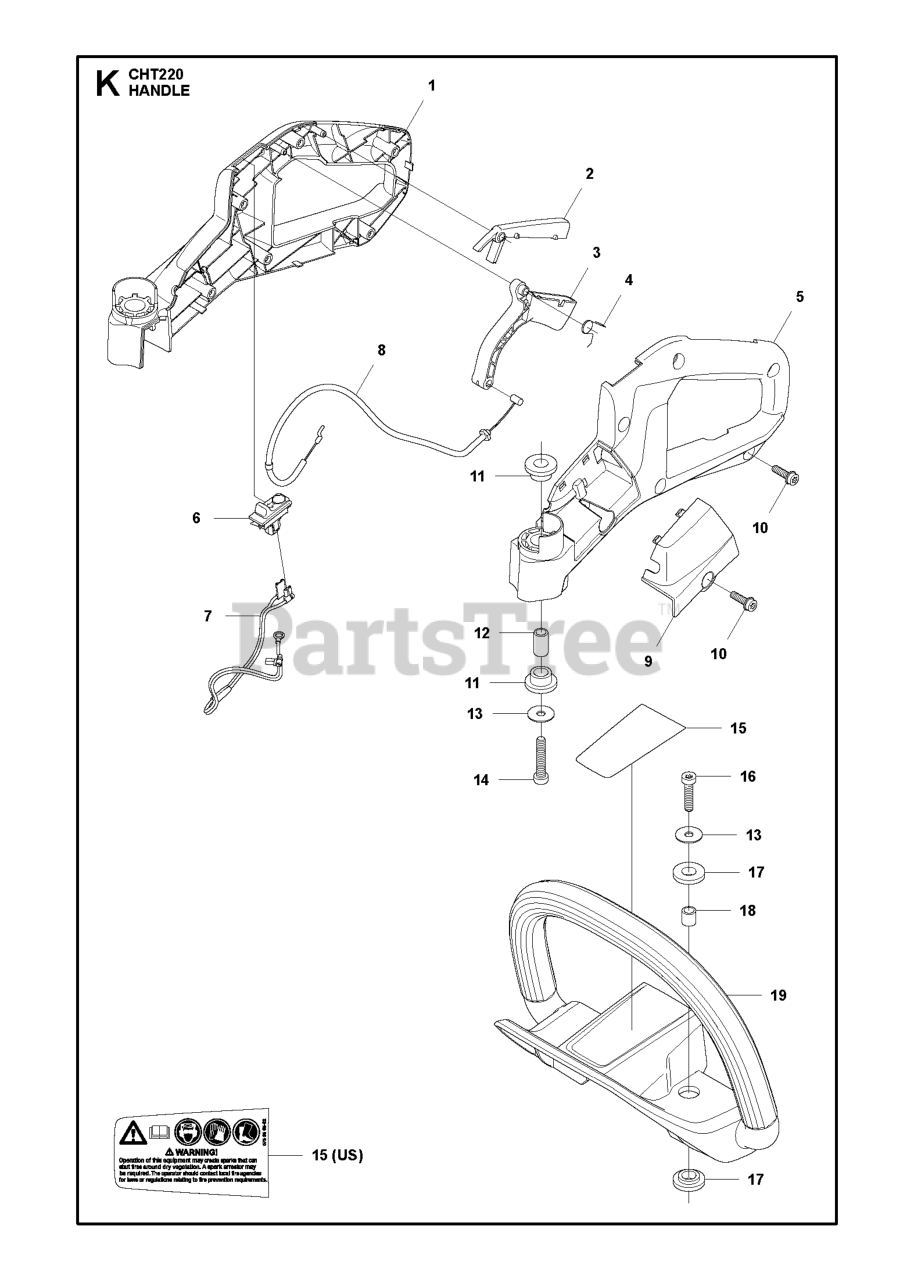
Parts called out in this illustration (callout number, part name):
1	REAR HANDLE
2	THROTTLE LOCKOUT
3	THROTTLE CONTROL
5	REAR HANDLE
6	STOP BUTTON
7	SHORT CIRCUIT CABLE
8	THROTTLE CABLE ASSY
11	ANTIVIBRATION ELEMENT
17	ANTIVIBRATION ELEMENT
